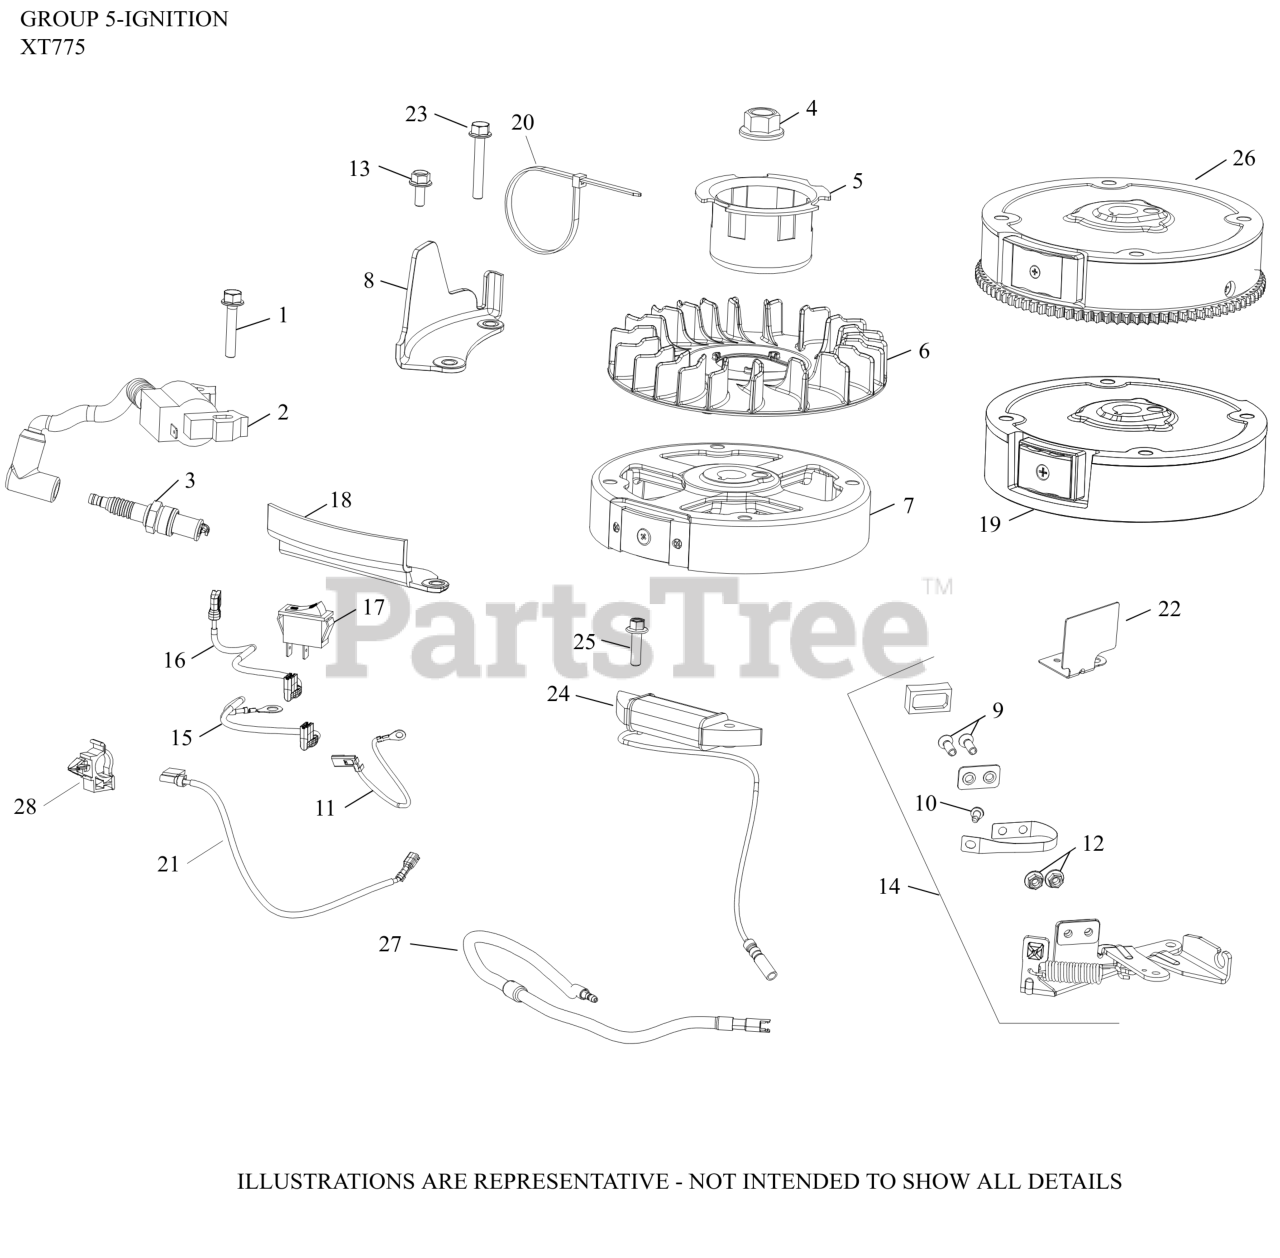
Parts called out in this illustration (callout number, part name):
1	SCREW, M6 X 25-(#25086436S)
2	MODULE IGN (#1458416S)
3	PLUG SPARK 12MM RFI
4	NUT, FLYWHEEL (W/SERRATIONS)
5	CUP, DRIVE - (#1410905S)
6	FAN, FLYWHEEL
8	GUARD, FINGER
15	LEAD,GROUND TO KILL (RCKR SWITCH)
16	LEAD, TOGGLE SWITCH KILL
17	SWITCH, ROCKER
18	GUARD, FINGER
19	FLYWHEEL (CAST IRON)
